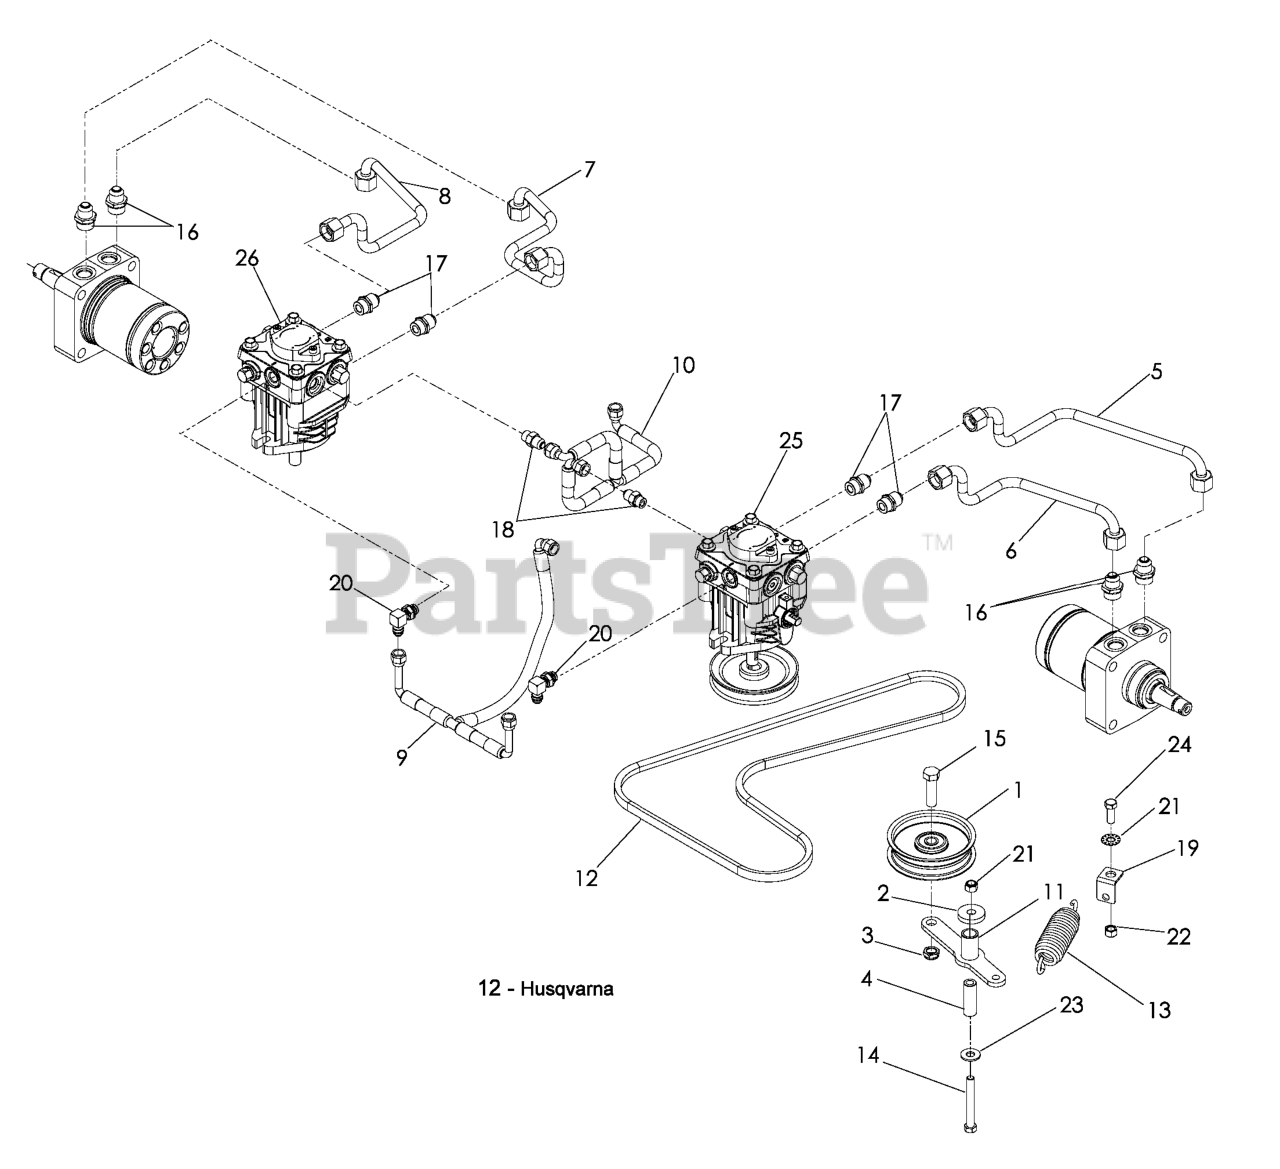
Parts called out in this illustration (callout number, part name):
1	PULLEY IDLER
2	WASHER .43X1.38X.25
3	NUT 1/2-13 HEX JM NYL
4	BUSHING 1.90
5	TUBE HYD. LH-A
6	TUBE HYD. LH-B
7	TUBE HYD. RH-A
8	TUBE HYD. RH-B
9	T-ASM HYD. SUCTION
10	T-ASM HYD. CASE DRAIN
11	WLDT BELT TENSIONER
13	SPRING
14	3/8-16 X 3` HHB
15	1/2-13X1-3/4 HHB GR. 5
16	FITTING HYDRAULIC
17	FITTING HYDRAULIC
18	FITTING HYDRAULIC
19	SPRING BRKT.
20	ADAPTER-MALE 9/16-18
21	3/8 INT/EXT.L-WASHER
22	NUT 3/8-16 NYLOC
23	WASHER 3/8 FLAT
24	HCS 3/8-16X1.GRD.5.ZD
25	HG_PUMP, BLACK BEAR LH
26	HG_PUMP, RH
